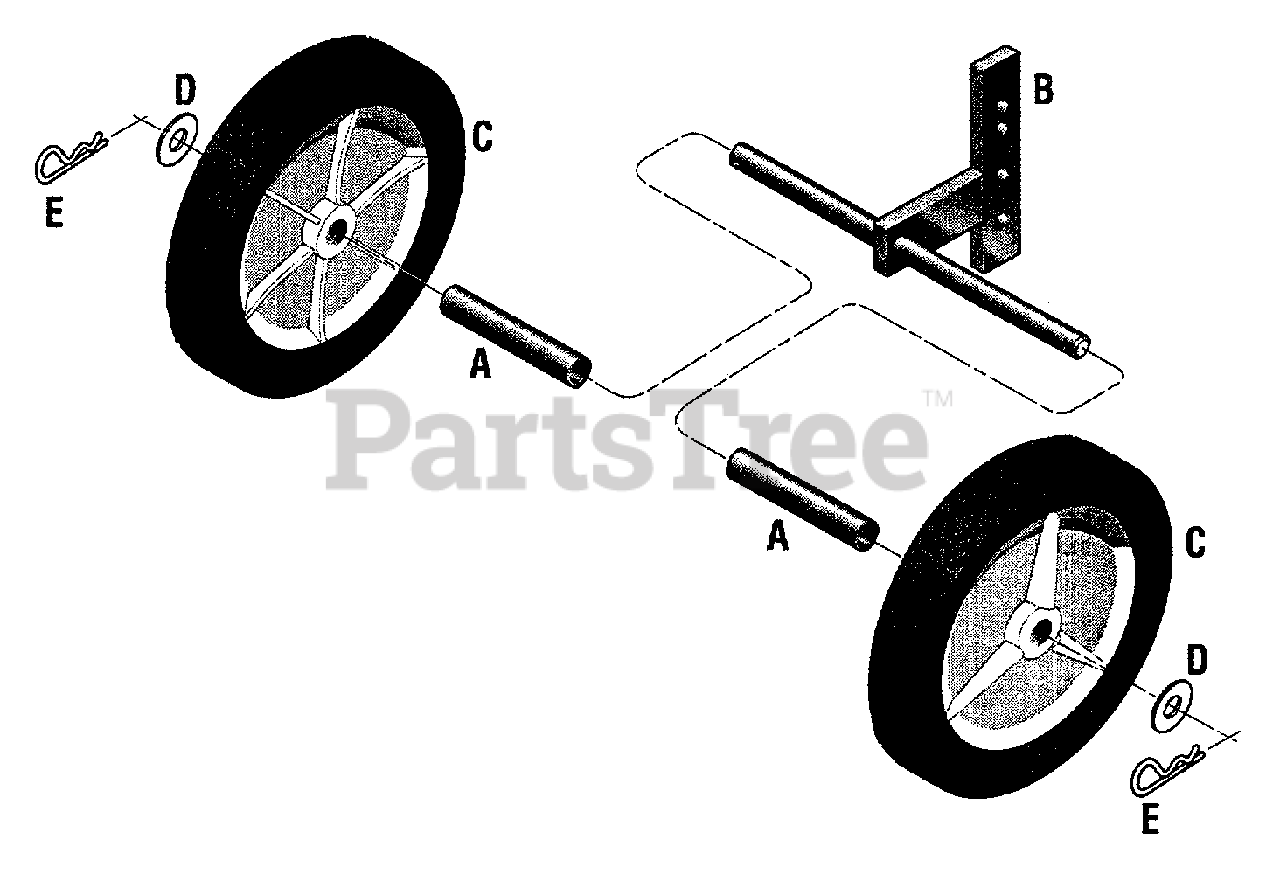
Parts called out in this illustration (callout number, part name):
A	Spacer, 1/2" I.D. x 2"
B	Wheel Bracket
D	1/2" Flat Washer
E	Hairpin Cotter
